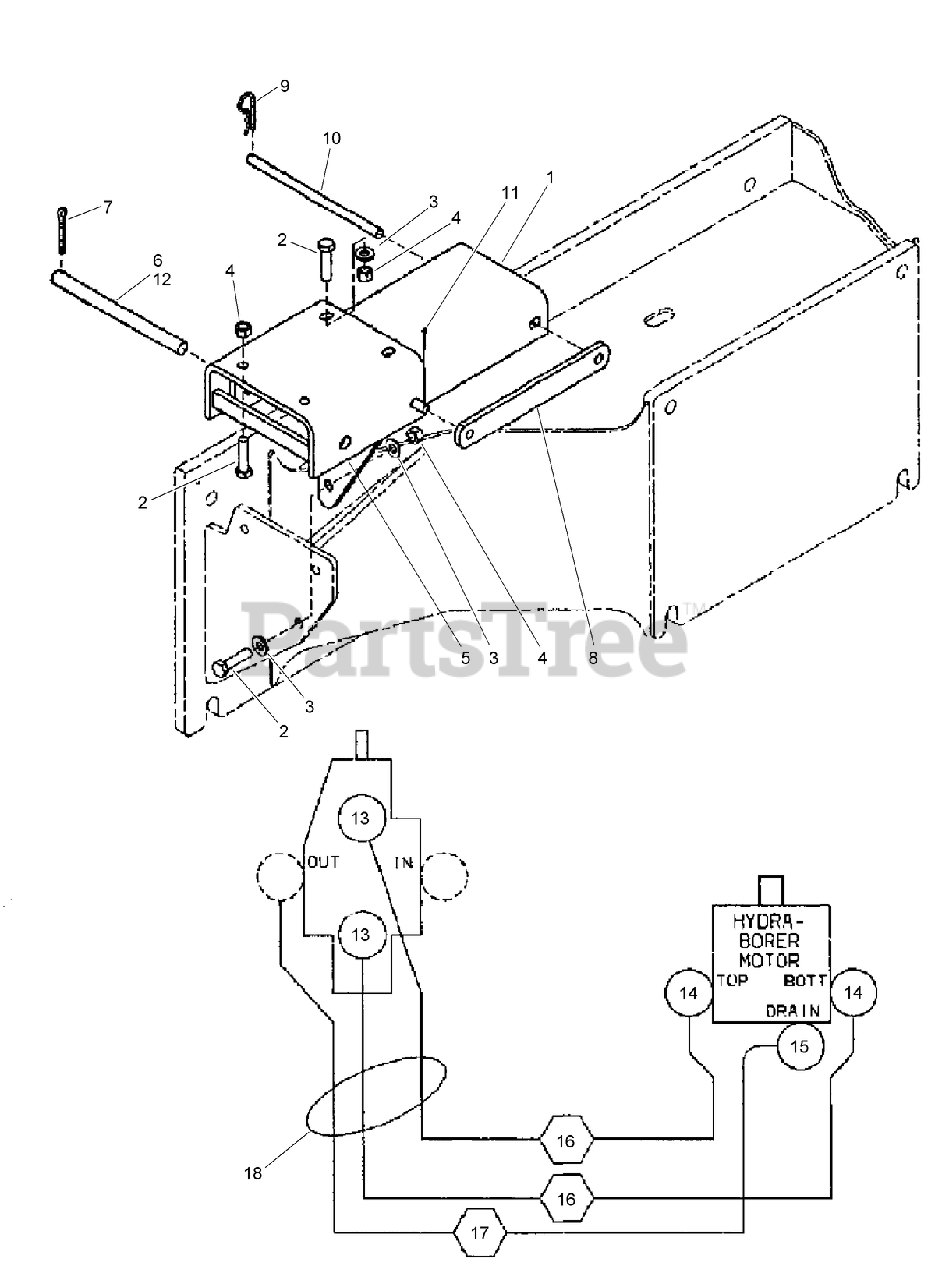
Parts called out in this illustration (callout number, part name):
1	WELDMENT-Frame, Mounting
3	WASHER-FLAT
4	NUT-HEX
5	WELDMENT-Hydra-Borer Mount
6	PIN-Pivot
7	PIN-Cotter, 0.25 x 1.50 in ZN
8	LINK-Hydra-Borer Support
9	PIN-Pivot
10	PIN-Hair
11	PIN-COTTER
12	WASHER-FLAT
13	CONNECTOR-Str Thd 5/8, 37FL-ORB 5/8
14	ELBOW-90 Adj 37FL 5/8 Tube
15	ELBOW-90 Deg
16	HOSE-Hydraulic
17	ASM-Hose, Tilt
18	STRAP-TIE
